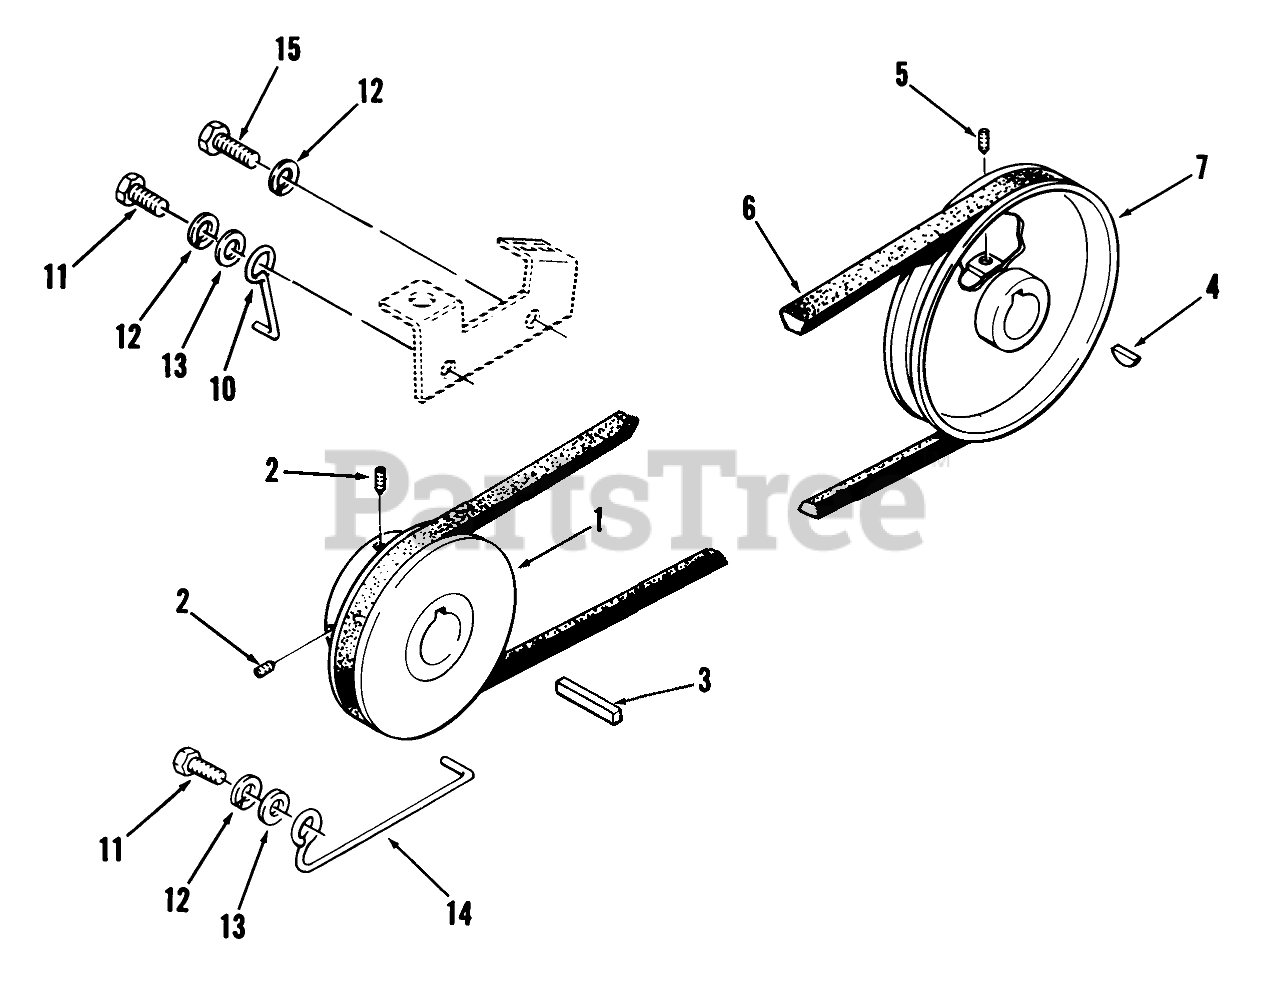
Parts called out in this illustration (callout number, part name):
1	Engine Drive Pulley
2	Set Screw
4	KEY-HI PRO
5	Set Screw
6	V BELT
7	PULLEY-TRANSMISSION
10	Belt Guide-Top
11	BOLT
12	LOCKWASHER
13	Washer
14	Belt Guide-Bottom
15	Bolt
